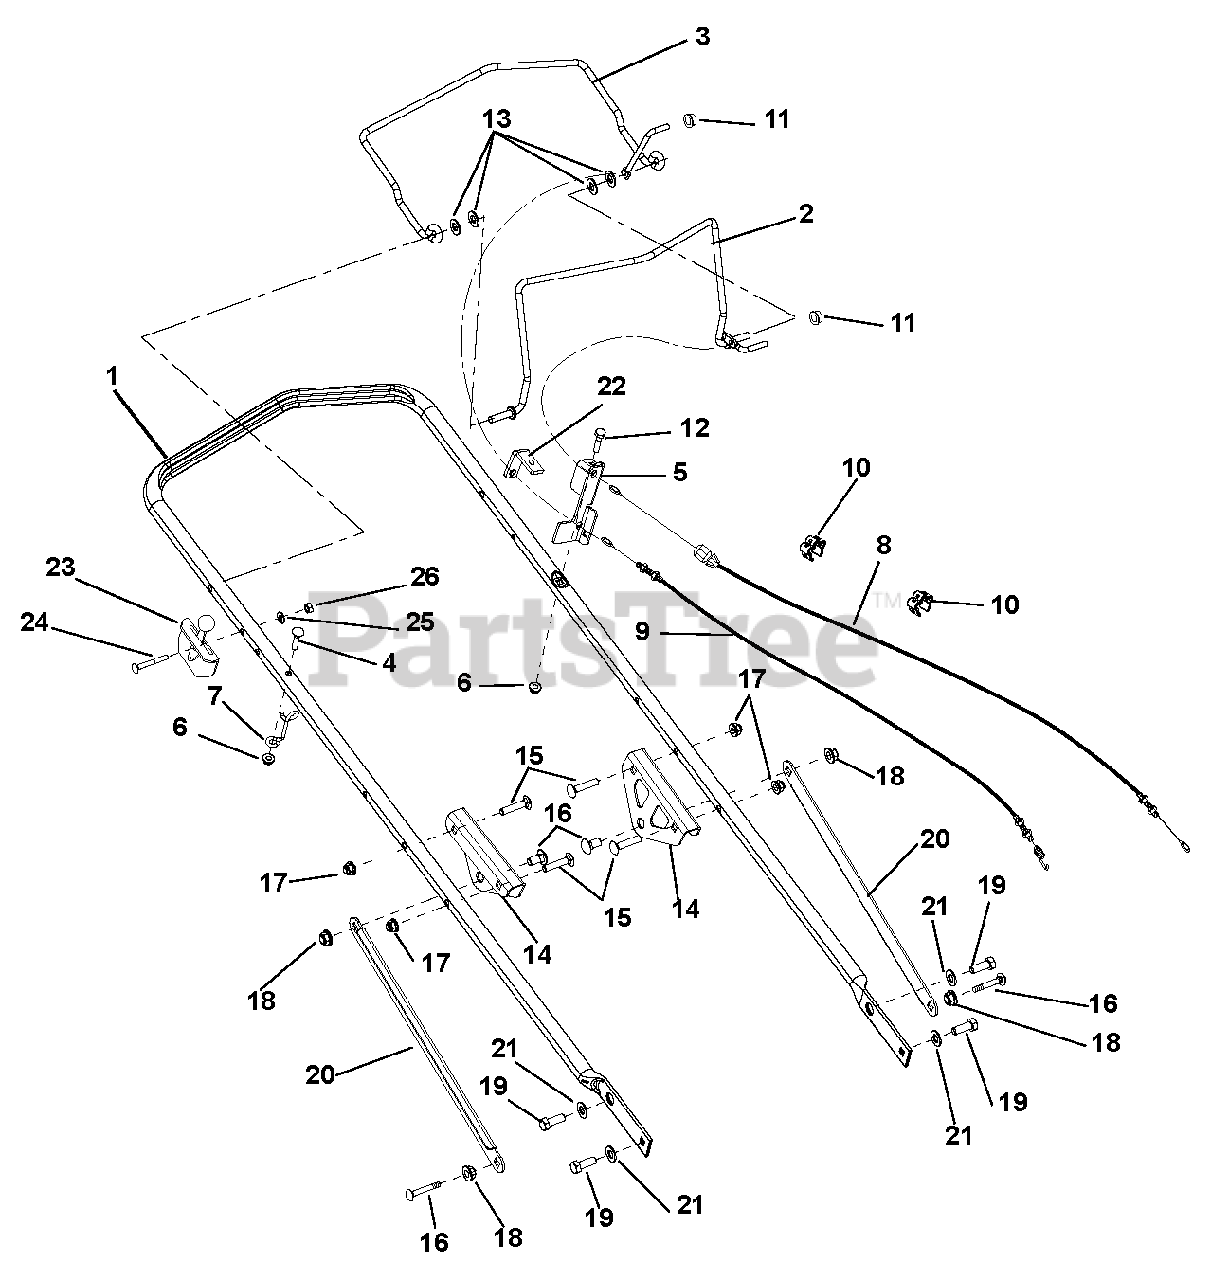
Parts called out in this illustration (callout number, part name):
1	Handlebar
2	Bail, Operator Presence
3	Bail, Clutch
4	Bolt, Round Head Square Neck .25-20 x 1.25
5	Anchor, Cable Thumb Adjustment
6	Nut, Locking, Top, Flange .25-20
7	Guide, Pullcord
8	Cable, Operator Presence Control
9	Cable, Commercial 21 Traction
10	Clip, Conduit
11	Push Nut, .25
12	Bolt, Hex .25-20 x 1.25
13	Washer, Flat-Steel .344 x .688 x .065
14	Bracket, Handlebar Reforcement
15	Bolt, Round Head Square Neck .31-18 x 1.50
16	Bolt, Round Head Square Neck .38-16 x .75
17	Nut, .31-18 Nyloc Flange
18	Nut, .38-16 Nyloc Flange
19	Bolt, Hex .38-16 x .75
20	Strap, Handlebar
21	Washer, Flat, Steel .406 x .812 x .065
22	Bracket, PTO Cable, Honda XD (911273)
23	Throttle Control, Honda (911273)
24	Bolt, Round Head Square Neck .25-20 x 1.75 (911273)
25	Washer, Flat, Steel .25 x .562 x .049 (911273)
26	Nut, Locking, Center .25-20 (911273)
